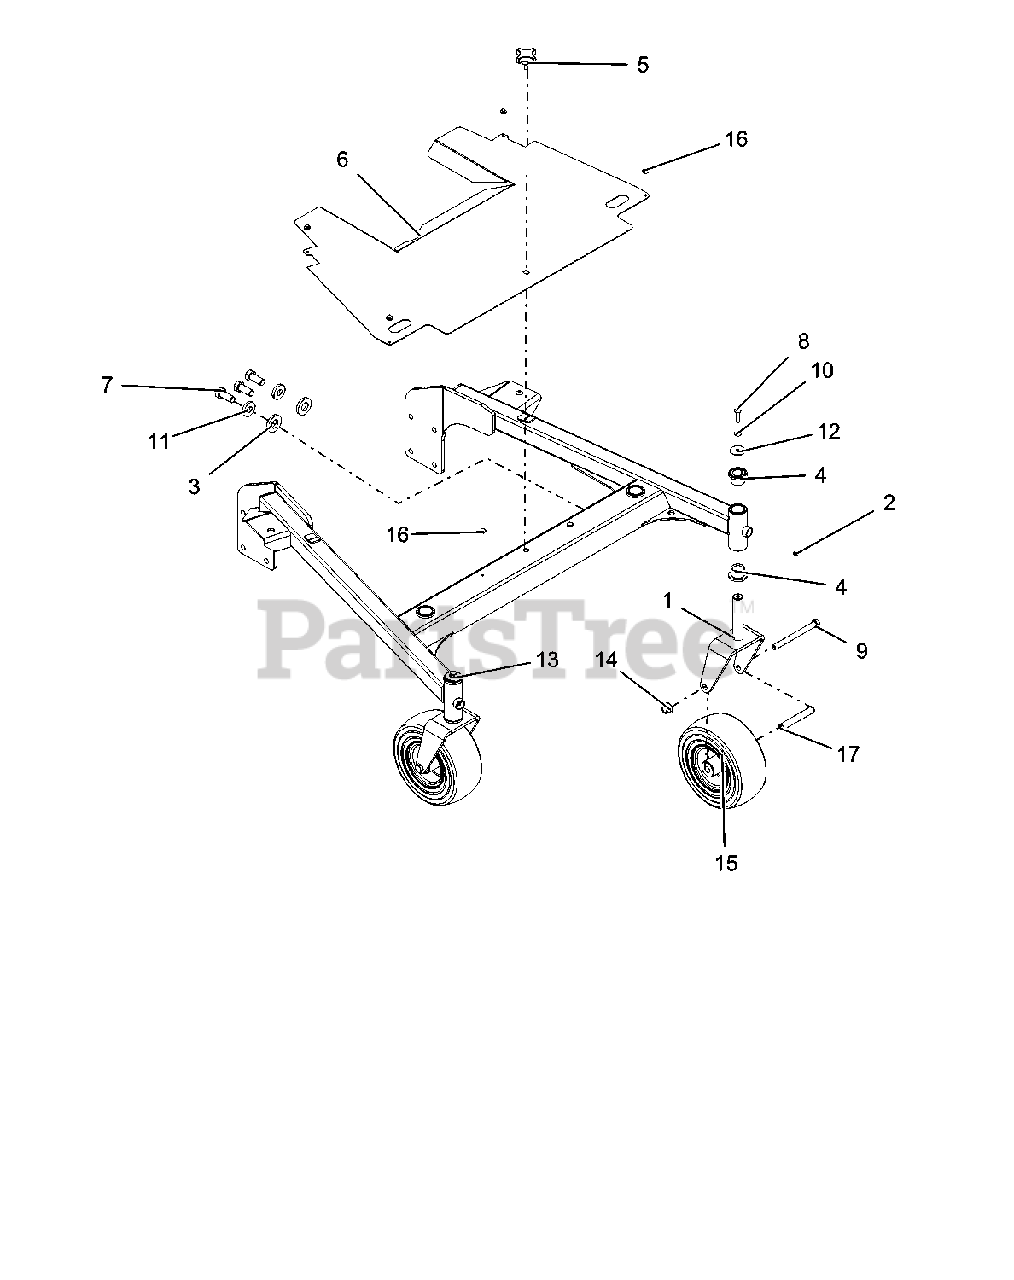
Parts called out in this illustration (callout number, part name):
1	WLDMT, FRONT WHEEL FLOAT WALK
2	FTG, 1/4-28 STRGT GREASE ZERK
3	WSHR-FL-STL .905X1.750X.25 YWZC
4	BRG, FLANGE 1.00 X 1.25 X 1.00
5	KNOB, 3/8-16 x .75
6	SHIELD, BELT 61" HYDRO WALK
7	BLT-HEX .62-11X1.50 GR8 YWZC
8	BLT-HEX .38-16X1.25 GR5 YWZC
9	BLT-HEX .50-13X5.50 GR5YWZC
10	WSHR-LK .38X.094 REG YWZC
11	WSHR-FL-STL .630X1.50X.25 YWZC
12	WSHR-FL-STL .380X1.50X.062 YWZ
13	WSHR-FL-STL .380X1.50X.125 YWZC
14	NUT-LK-NYL-FLG .50-13 YWZC
15	9X3.5-4 CAREFREE BLT TOGETHER
16	BUMPER GROMMET .125 X .25 REV
17	TUBE, CASTER AXLE
